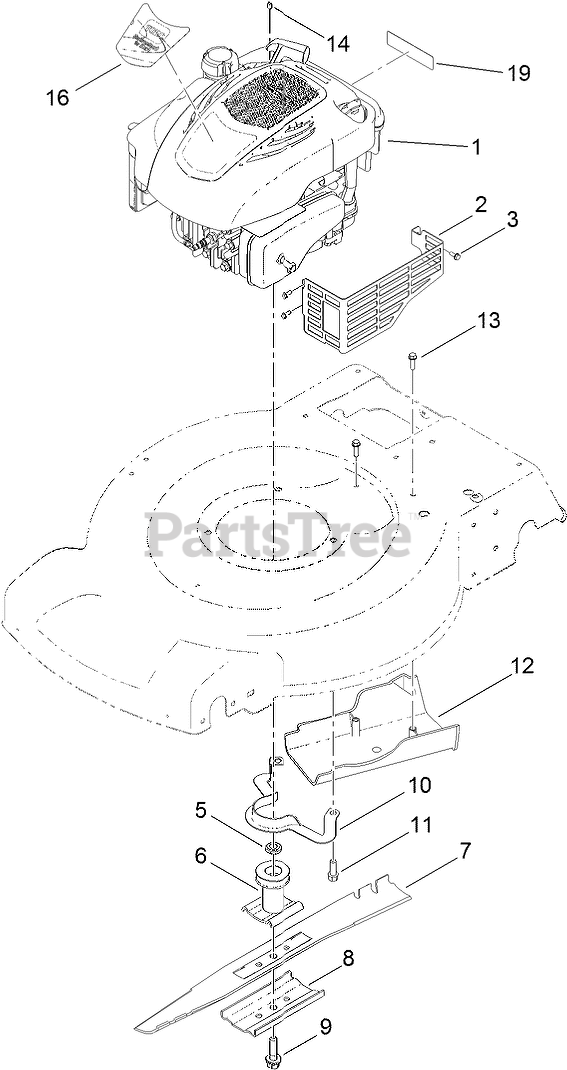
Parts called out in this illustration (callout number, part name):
2	SHIELD-MUFFLER
3	SCREW-TAPTITE
5	Spacer-Driver
6	DRIVER-BLADE
7	BLADE-22 INCH
8	SUPPORT-BLADE
9	BOLT-BLADE
10	Guide-Belt
11	SCREW-TAPTITE
12	COVER-BELT
13	SCREW-HWH
14	STOP-ROPE
16	DECAL-SHROUD
19	DECAL-ARRESTER, SPARK
